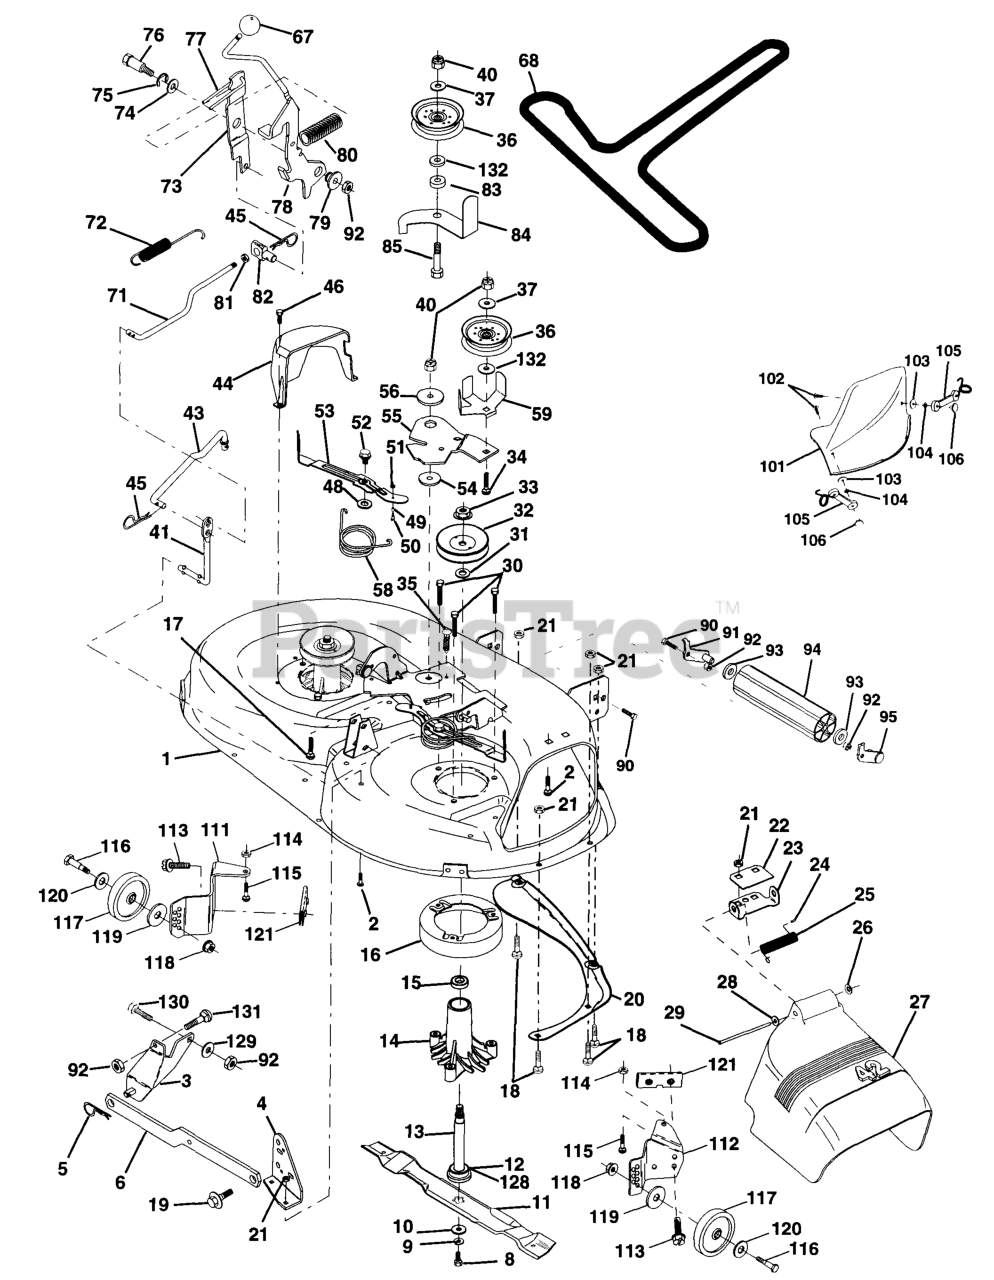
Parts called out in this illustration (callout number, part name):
1	DECK 42"
2	RP BOLT 5/16-18 X3/4 ZN/YEL GR
3	Bracket Asm Fr Sway Sar 38/42
4	BRKT DECK SW BAR
5	RETAINER-SPRNG RB
6	REAR SUSP ARM
8	BLADE BOLT
9	LOCKWASHER
10	WASHER.BLADE
11	BLADE.42".MULCH
12	BEARING.BALL.#6204.(MANDREL)
13	SHAFT ASM VENT
14	HOUSING.MANDREL.VENTED (MACHD)
16	STRIPPER
17	BOLT
18	BOLT
19	BOLT SHD 5/16-18
20	BAFFLE
21	LOCKNUT
22	STIFFENER BRACKET
23	DEFLECTOR BRACKET
24	CAP-SLEEVE LT
25	SPRING TORSION
26	NUT PUSH M
27	SHIELD.DEFLECTOR.MOWER.42".BLK
28	Washer 11/32 X 5/8 X 16 Ga
29	ROD.HINGE
30	SCREW
31	WASHER
32	PULLEY/MANDREL
33	NUT
35	FASTENER.XMAS.TREE
36	FLAT IDLER PULLEY
37	WASHER
43	CLUTCH ROD
44	GUARD MANDREL LH BLACK
45	RETAINER M
46	SCREW.1/4-20X5/8
49	ROLLER ASSY
52	BOLT.SHOULDER.5/16-18
53	ARM ASM PAD BRAD
54	HARDENED WASHER
55	ARM IDLER 42" MOWER LT/YT
56	SPACER RETAINER
59	GUARD, BELT
67	KNOB T (1/2-HOLE)
68	V-BELT TRIPATH
71	CLUTCH ROD
72	RETURN SPRING
73	ARM CLUTCH SECONDARY
77	KEEPER SPRING
78	CLUTCH ARM
79	BUSHING.FLANGE.E-RING.GROOVE
80	SPRING-CLUTCH (2 2 PW01)
81	NUT
82	TRUNNION.ADJUSTABLE.3/8-16
84	KEEPER BELT
85	BOLT
90	BOLT
91	BRACKET LH (A)
92	NUT
93	Washer 17/32 x 7/8 x 16 Ga.
94	NOSE ROLLER
95	BRACKET RH (B)
101	COVER MULCH 42"
102	SCREW
104	LOCKWASHER #10
105	LATCH ASSEMBLY
106	WELDNUT
111	BRACKET WHEEL GAUGE LH 42" DK
112	BRACKET WHEEL GAUGE RH 42" DK
113	SCREW.THDROL.5/16-18X3/4.TTY
114	NUT
115	BOLT.CARR.5/16-18X1/2
116	BOLT M
117	WHEEL.GAUGE.BLK.4.93
118	LOCKNUT
119	WASHER.5/16.FLAT.STE.STD.
120	Washer17/32 x 15/16 x 12Ga.
121	BRACKET.EXTRUDED.GAGE.WHEEL
128	WASHER FELT
129	WASHER
130	BOLT
131	BOLT D
